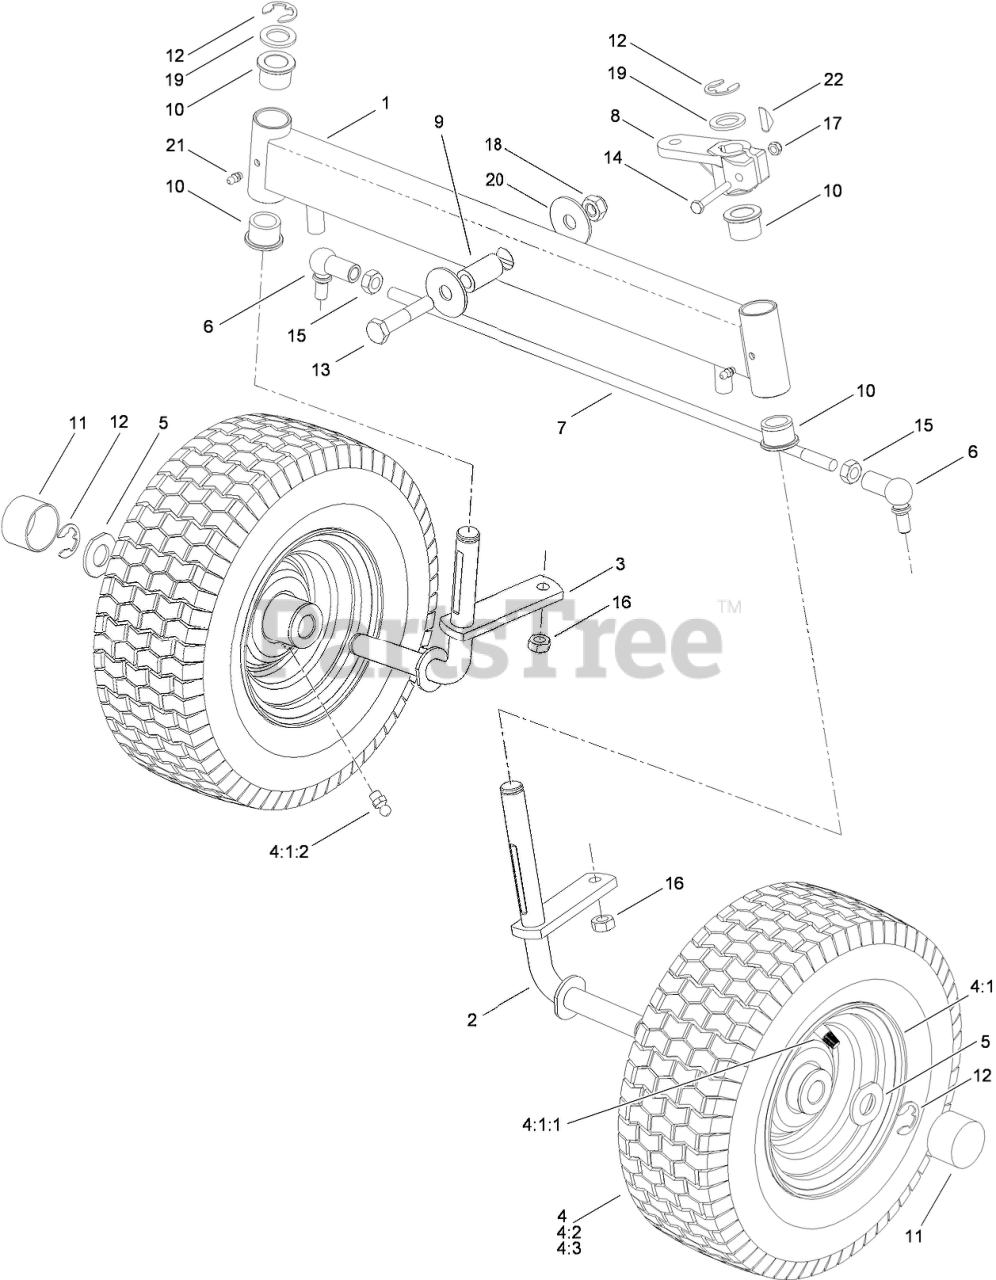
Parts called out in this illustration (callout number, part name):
1	FRONT AXLE ASM
2	SPINDLE-LH
3	SPINDLE-RH
4	WHEEL ASM
4:1	FRONT RIM ASM
4:1:1	Valve-Tire
4:1:2	FITTING-GREASE
5	RETAINER-CAP, HUB
6	JOINT-BALL, ANGLE
7	TIE ROD-AXLE, FRONT
8	LEVER-SPINDLE, STEERING
9	SPACER
10	BUSHING-SWIVEL
11	CAP-HUB
12	CLIP-SPRING
13	SCREW-HH
14	SCREW-HH
15	NUT-HEX
16	NUT-LOCK, NI
17	NUT-LOCK
18	NUT-LOCK, HEX NI
19	WASHER-FLAT
20	WASHER
21	FITTING-GREASE
22	KEY-WOODRUFF
